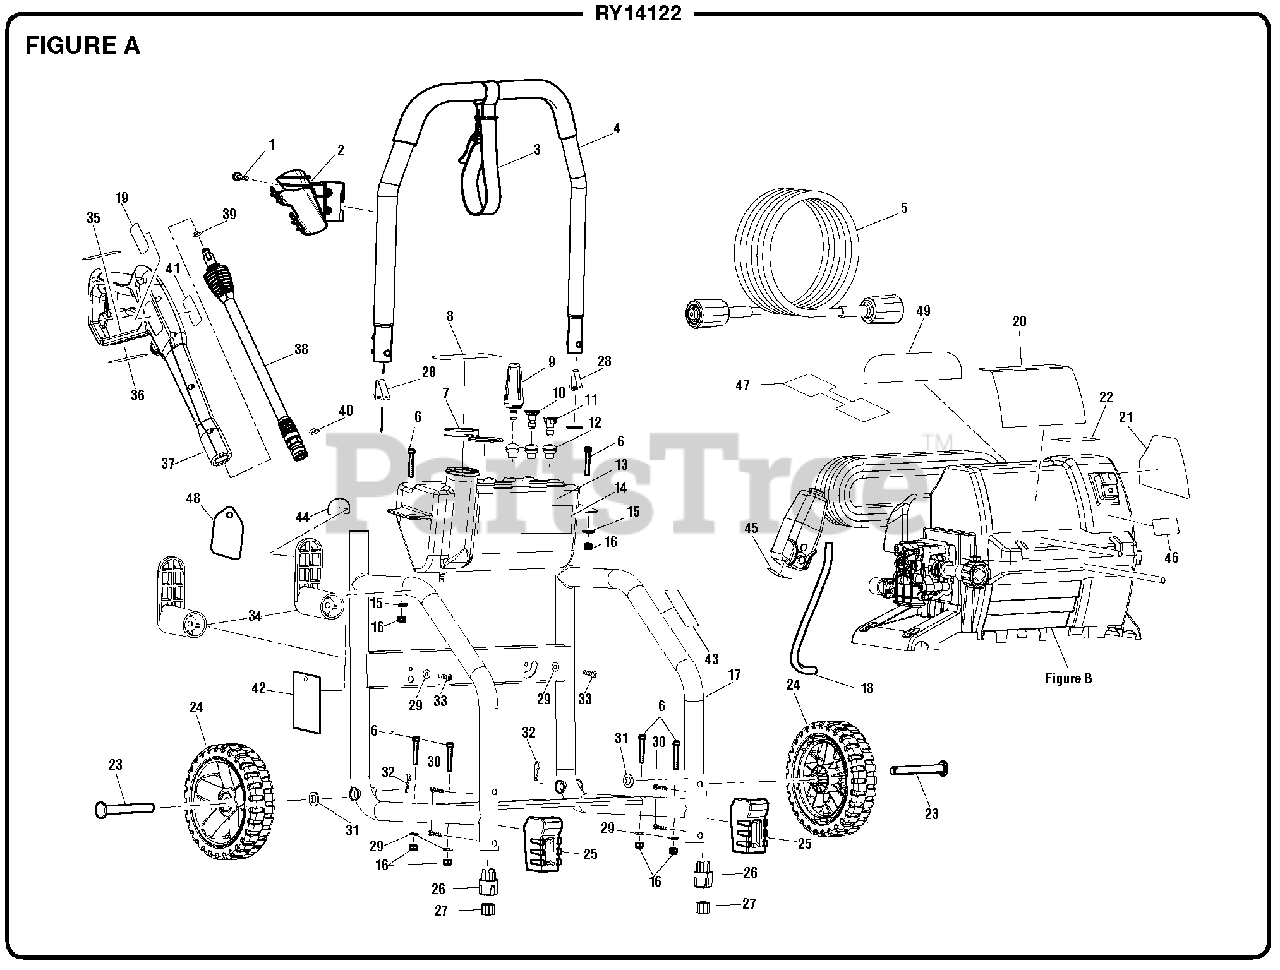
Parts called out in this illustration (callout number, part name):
1	Bolt (M6 x 20 mm)
2	Trigger Handle Holder
3	Hose Storage Strap
4	Handle Assembly
5	High Pressure Hose
6	Screw (M6 x 40 mm)
7	Detergent Tank Cap
8	Quick Start Label
9	Turbo Nozzle
10	Soap Nozzle
11	15deg Nozzle
12	Nozzle Grommet
13	Detergent Tank Assembly
14	Performance Label
15	Washer (M6)
16	Lock Nut (M6)
17	Main Frame
18	Detergent Hose
19	Trigger Handle Logo Label
20	Ryobi Logo Label
21	Danger Label
22	Soap Dilution Label
23	Wheel Axle
25	Foot Cover
26	Foot (Inc. Key No. 27)
28	Spring Clip w/Button
29	Washer (M6)
30	Screw (M3.5 x 20 mm)
31	Washer (2 in.)
32	Hitch Pin
33	Screw (ST4.8 x 19 mm)
34	Cord Wrap Arm
35	Trigger Handle Warning Label (French/Spanish)
36	Trigger Handle Rating Label
37	Trigger Handle
38	Spray Wand
39	O-Ring (7.1 mm x 2.65 mm)
40	O-Ring (9.2 mm x 2.4 mm)
41	Trigger Handle Warning Label (English)
42	Warning Hangtag
43	Inquires Label
44	Cord Unlock Label
45	Cord Plug Label
46	On/Off Switch Label
47	Cord Wrap Label
48	Nozzle Hang Tag
49	Nozzle Selection Label
